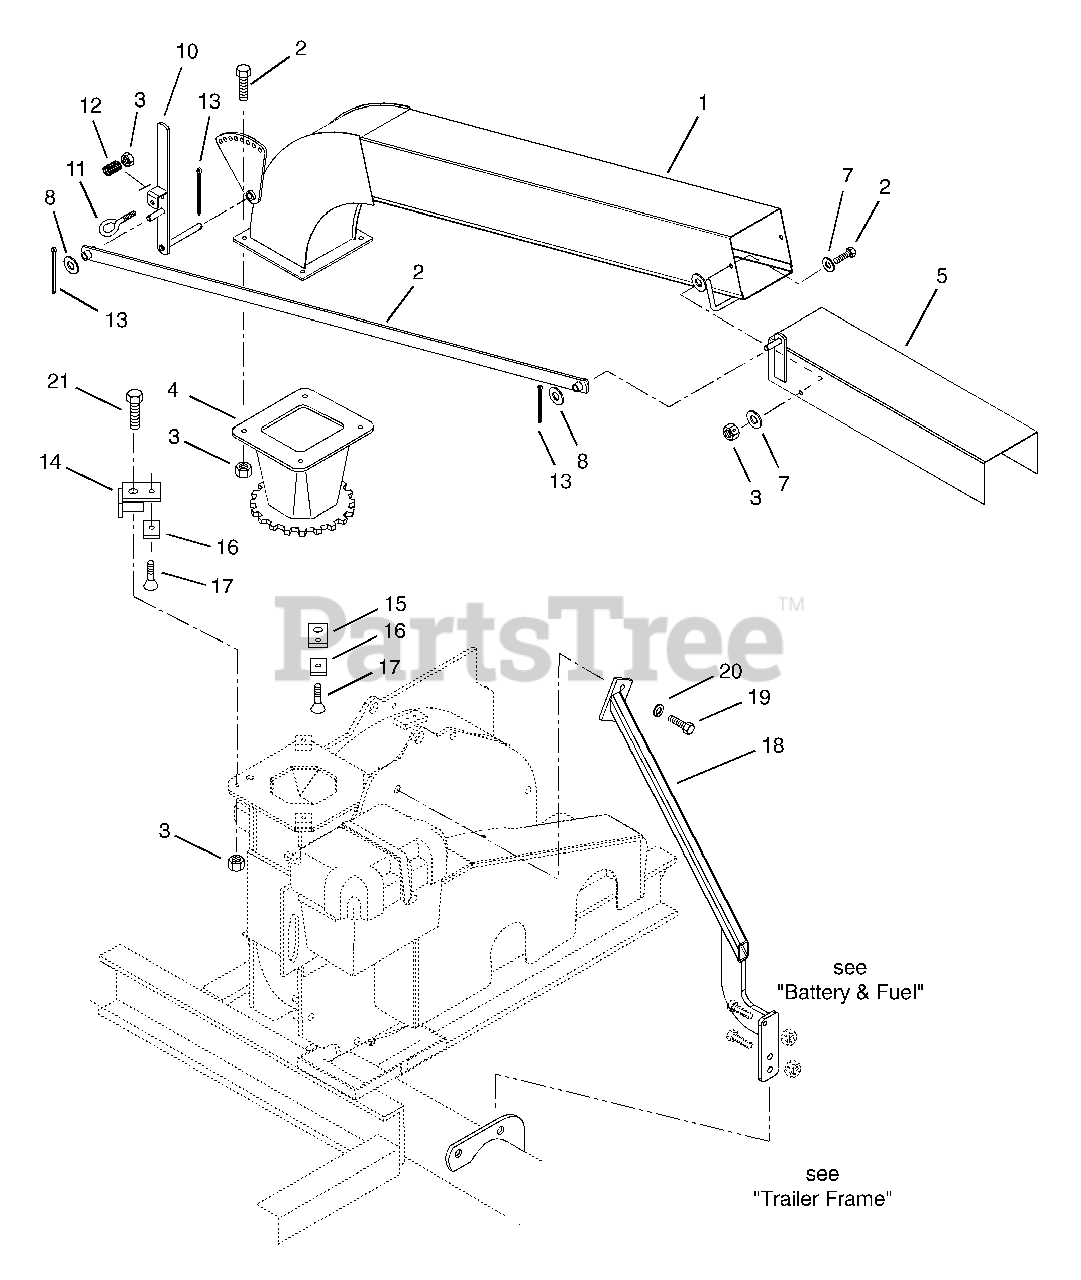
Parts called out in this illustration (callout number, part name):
1	Tube-Discharge
2	Bolt-Hex .38-16 x 1.00 Grade 5
3	Nut-Locking-Center .38-16
4	Vertical Discharge Riser Weldment
5	Bonnet Weldment
6	Washer-Flat-Nylon .38 x 1.00 x .083
7	Washer-Flat-Steel .438 x 1.00 x .083
8	Washer-Flat-Steel .563 x 1.38 x .109
9	Lever-Control Weldment
10	Handle-Adjustment Weldment
11	Bolt-Eye .375-16 x .50
12	Spring-Compression .045 x .50 x 1.187
13	Pin-Cotter .12 x 1.00
14	Discharge Retainer Weldment
15	Retainer-Discharge
16	Pad-Discharge Retainer
17	Screw-Machine-Flat Countersunk Head .25-20 x .50
19	Bolt-Hex .50-13 x 1.75 Grade 5
20	Washer-Locking .50 x .125
21	Bolt-Hex .38-16 x 2.00 Grade 5
